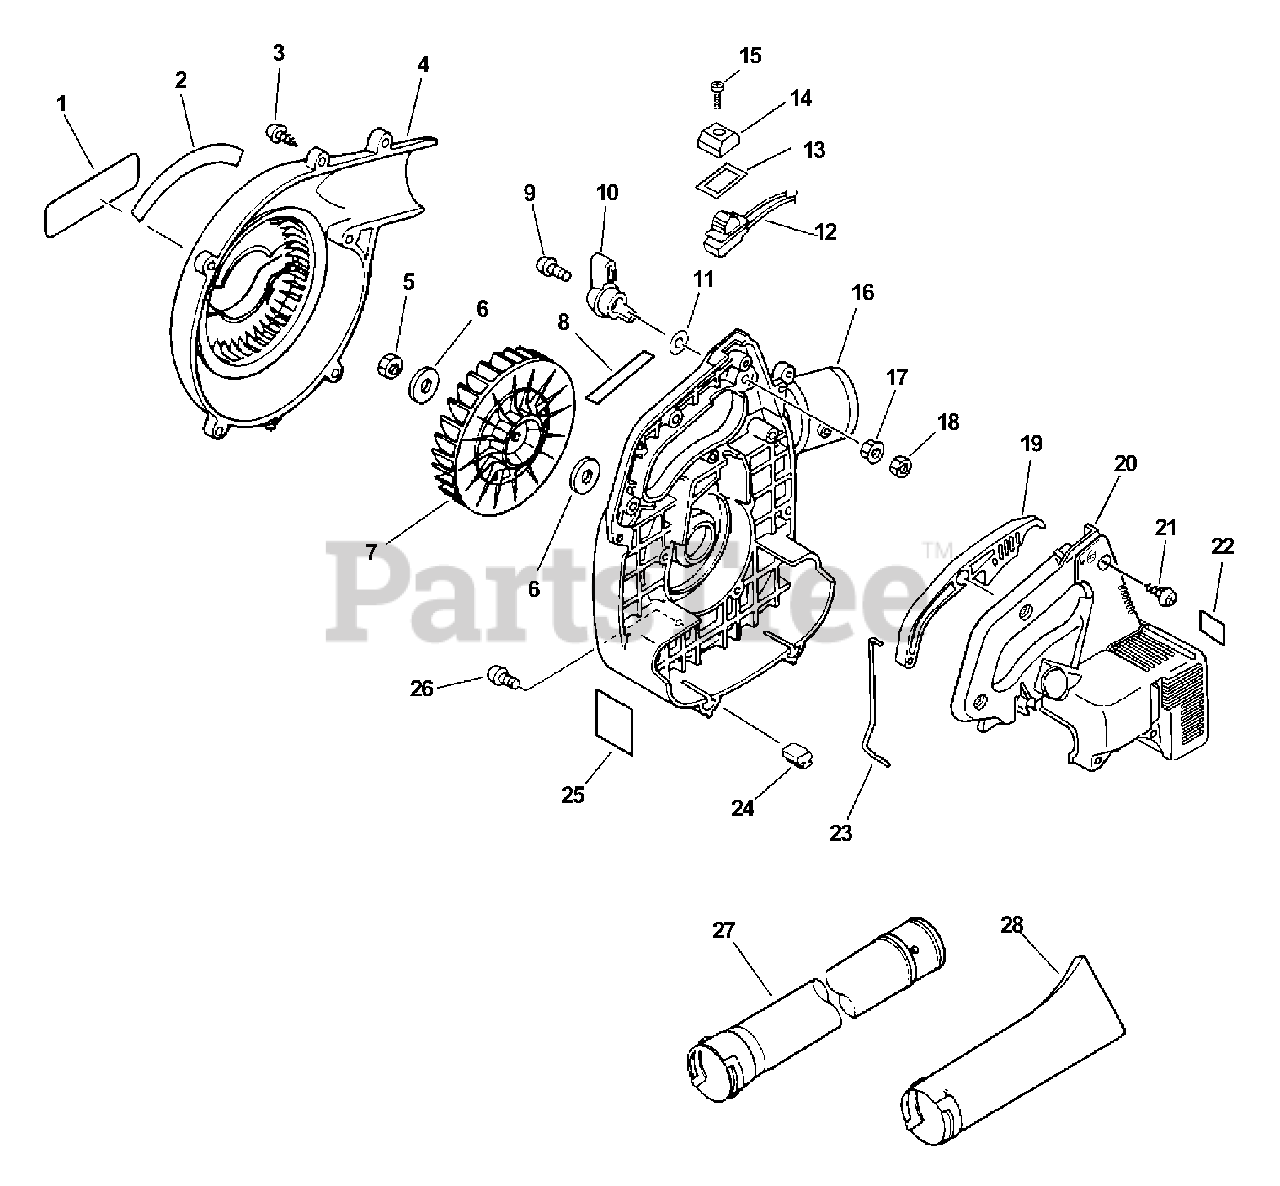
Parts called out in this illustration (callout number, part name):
1	LABEL - ECHO
2	LABEL - MODEL
3	SCREW - 5X20 -- TAPPING
4	COVER, FAN - LEFT
6	WASHER - 8
8	LABEL - NOISE 65dB(A) CAT I
9	SCREW - 5X25
10	LEVER, THROTTLE - ORANGE
11	WASHER - 5
12	IGNITION SWITCH ASSY
13	COVER, SWITCH - STOP
14	KNOB, SWITCH - ORANGE
15	SCREW - 3X10
16	COVER, FAN - RIGHT
17	NUT - 5 -- FLANGE
19	TRIGGER, THROTTLE - ORANGE
20	COVER, ENGINE
21	SCREW - 5X20 -- TAPPING
22	LABEL - HOT SURFACE
23	ROD, THROTTLE
25	LABEL - CAUTION
26	SCREW - 4X22
27	TUBE, BLOWER - STRAIGHT
28	TUBE, BLOWER - NOZZLE
